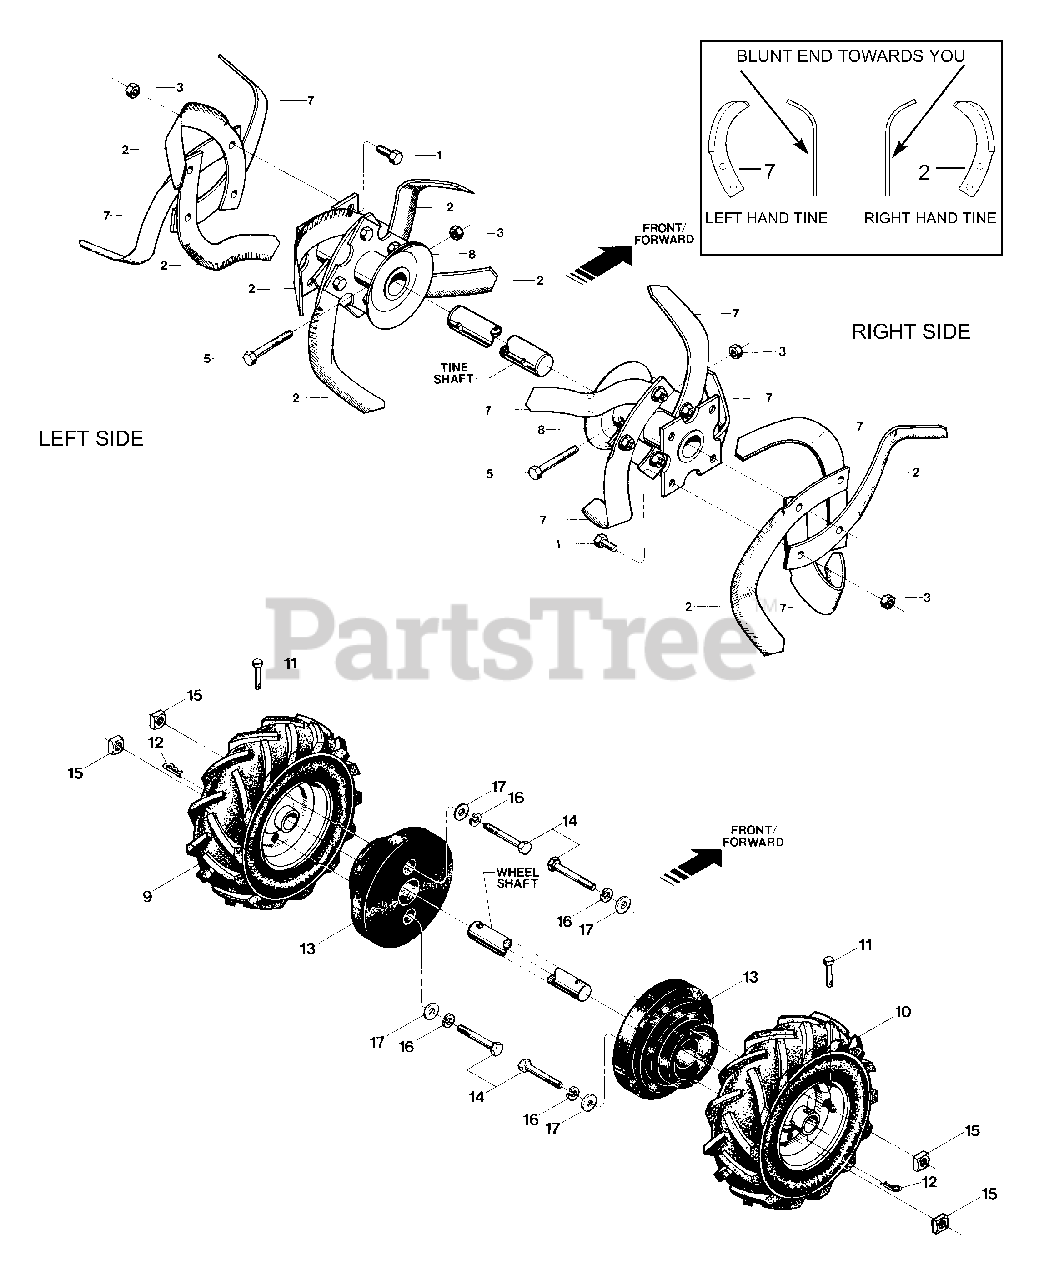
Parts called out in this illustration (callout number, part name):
1	Screw, hex hd., 3/8-16 x 1- 1/4, Grade 5
2	Bolo Tine, single, right hand
3	Nut, hex locking, 3/8-16
5	Screw, hex hd., 3/8-16 x 2, Grade 8
7	Bolo Tine, single, left hand
8	Tine Holder
9	Wheel and Tire Assembly, left side, 5.0 x 6" tire mounted on 6" grey wheel, tubeless, valve stem, tractor tread
10	Wheel and Tire Assembly, right side, 5.0 x 6" tire mounted on 6" grey wheel, tubeless, valve stem, tractor tread
11	Clevis Pin, .312 x 1- 3/4
12	Hitch Pin
13	Wheel weight, 16-1/2 lbs.
14	Screw, hex hd., 3/8-16 x 3
15	Nut, 3/8-16
16	Lockwasher, 3/8
17	Washer, plain (flat), 3/8
